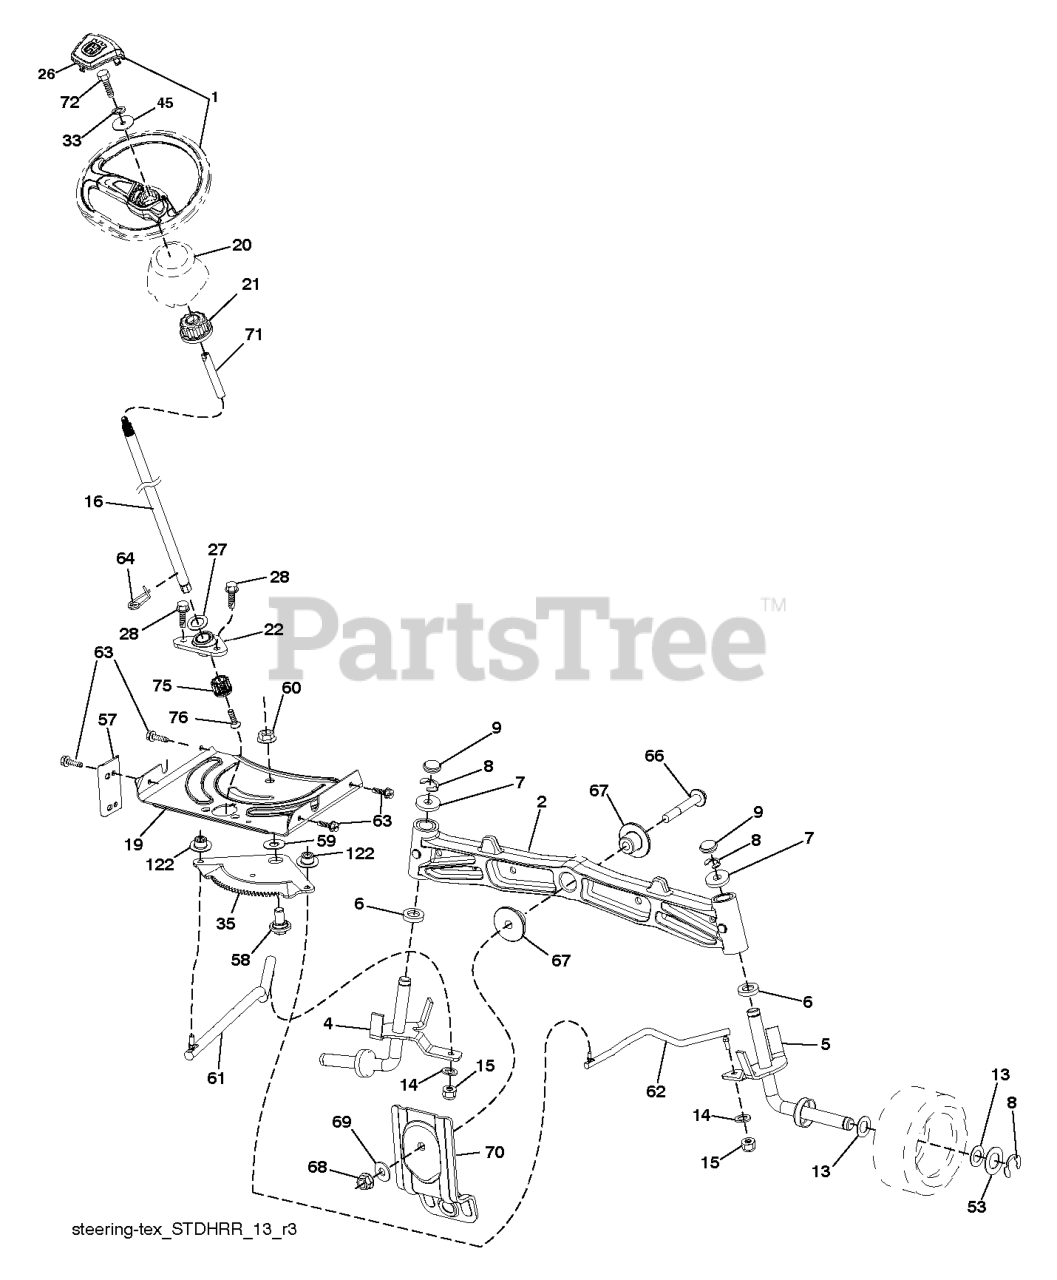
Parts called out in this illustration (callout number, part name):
1	Service Kit
2	AXLE.CAST.IRON
4	SPINDLE.STEERING.ASM.LH.13".TI
5	SPINDLE.STEERING.ASM.RH.13".TI
6	WASHER THRUST
9	CAP.SPINDLE.BLACK
15	NUT CROWNLOCK 3/8-24
16	3 HIGH.SHAFT-ZINC.PLATED
19	PLATE.STEER.DDL.NLT/NG
20	STEERING.BOOT.HUSQ.LT
21	ADAPTER, WHEEL STNG..
22	BEARING.SHAFT.STEER.LOWER.625
28	SCREW, 3/8-16X3/4
33	WASHER SPRING LOCK WASHER WITH
35	GEAR.SECTOR.PLATE.DDL.
53	WASHER.HARDENED
57	BRACKET.UPSTOP.TEX
58	BOLT.SHOULDER.SECTOR.P
59	WASHER.THURST.SECTOR.S
60	NUT FLANGE LOCK 5/8-11
61	LINK.ASM.DRAG.ADJUST.LH.PLATED
62	LINK.ASM.DRAG.ADJUST.RH.PLATED
63	SCREW
64	RETAINER.CLIP.SPRING.S
66	BOLT HEX FGHD 7/16-14 X 3 SERR
67	BUSHING.PM.FRONT AXLE
68	NUT.LOCK.FLANGE.7/16
69	WASHER.1.5X.505X.118
70	BRACKET.SUSP.MWR.FRT.30"SRD
71	SHAFT.EXTEN.STRG.SPLINE
75	PINION.ZINC PLATED
76	SCREW HEAD SOCKET LRVB
122	CAP.GEAR.SECTOR.TEX
